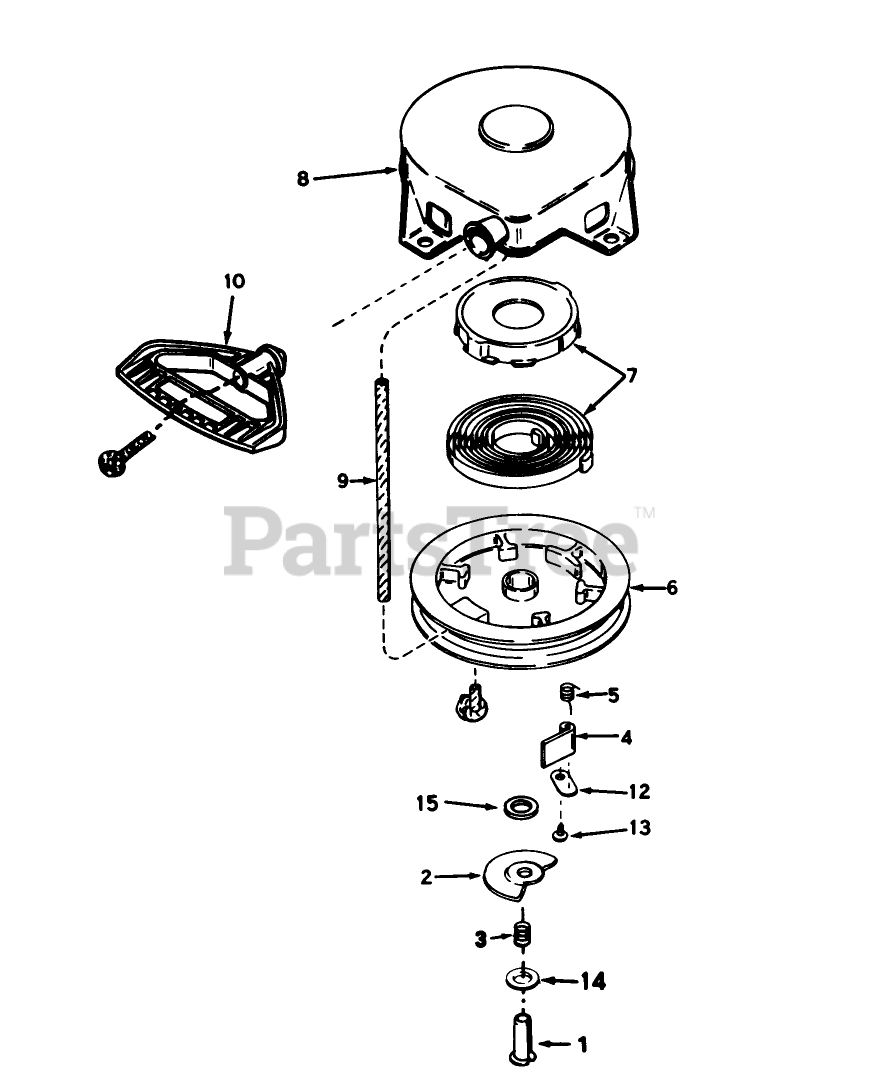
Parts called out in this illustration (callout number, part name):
1	Pin, Spring (Incl. Ref. #7)
2	Washer
3	Brake Spring
4	Dog-Starter
5	Spring-Dog
6	Pulley
7	Spring Keeper Assy
8	Housing-Starter
9	Rope-Starter
10	Handle-Starter, Mitten Grip
12	Retainer-Dog
13	Screw
14	Washer
15	Washer
